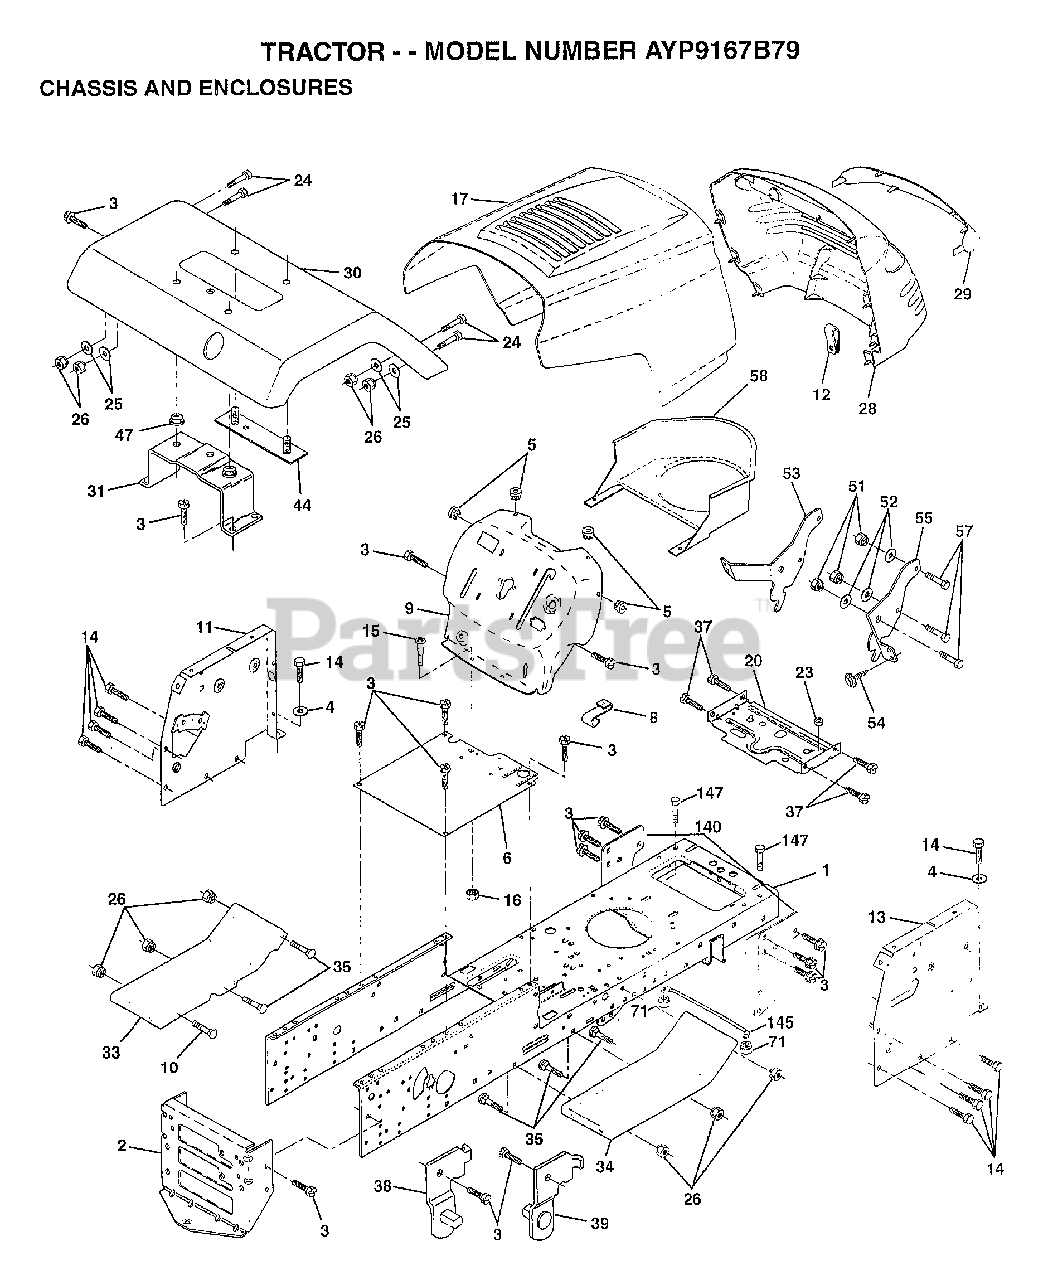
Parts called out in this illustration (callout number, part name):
1	CHASSIS ASM
3	SCREW
4	WASHER
5	BUMPER-HOOD/DASH
6	SADDLE
8	"CLIP,INSULATOR"
9	DASH SILKSCREEN
11	"PANEL-DASH,LH"
12	CLIP.TINNERMAN
13	"PANEL-DASH,RH"
14	SCREW LT
15	SCREW
17	HOOD.STL.PRV.LB
20	PLATE MEG BATTERY/FUEL TANK
24	BOLT
25	WASHER
26	NUT
28	GRILL
29	LENS.EURO.W/DECAL
31	BRKT.ASM.FENDER
33	FOOTREST.LT.LT/GT
34	FOOTREST.RH.LT/GT
35	BOLT
37	SCREW LT
38	BRACKET ASM LH
39	BRACKET ASM RH
44	STRAP ASM FENDER
47	NUT-PUSH YT
51	NUT
52	WASHER
53	BRACKET.GRILLE.LH
55	BRACKET.GRILLE.RH
58	AIR DUCT
140	BRKT SUSPENSION
145	"ROD POVOT,CHASSIS"
147	BOLT LT
